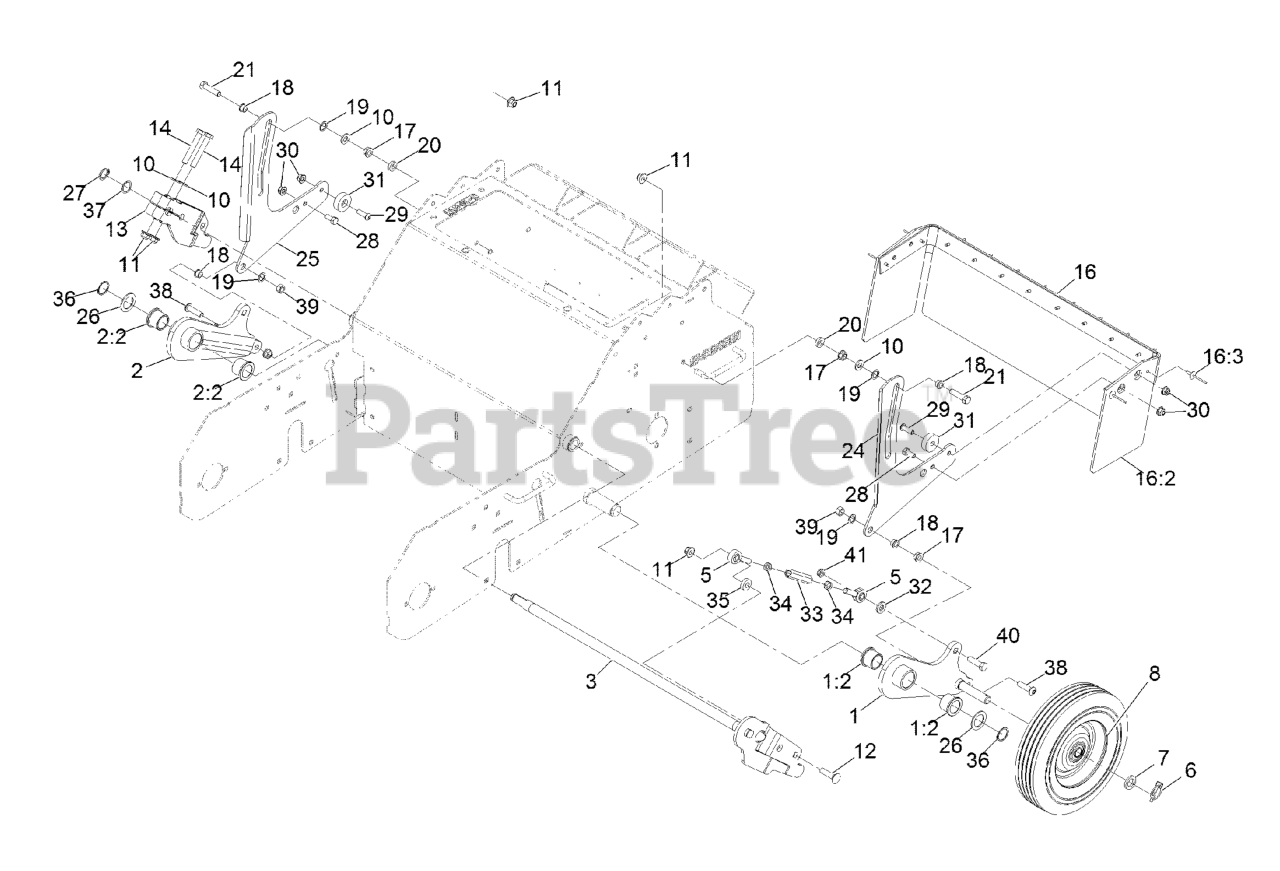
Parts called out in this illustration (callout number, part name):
1	LH WHEEL ARM ASM
1:2	BUSHING-FLANGE
2	RH WHEEL ARM ASM
2:2	BUSHING-FLANGE
3	PIVOT SHAFT ASM
5	BALLJOINT
6	PIN-KLIK
7	SPACER-BEARING
8	WHEEL, TRANSPORT
10	WASHER-FLAT
11	NUT-HF, NI
12	SCREW-CARR
13	ARM-LIFT, RH
14	SCREW-HH
16	GUARD-FOOT
16:2	FOOT-SHIELD
16:3	RIVET-POP
17	NUT-HHF, WHIZ
18	BUSHING-FLANGED
19	WASHER-NYLON
21	SCREW-HH
24	GUARD-ARM, LH
25	GUARD-ARM, RH
26	WASHER-SPACER
27	RING-RETAINING
28	SCREW-HH
29	SCREW-HSBH
30	NUT-HF, NI
31	GUIDE-ARM, TRAIL
33	ROD-LIFT LINK
34	NUT-HJ
35	SPACER
36	RING-RETAINING
37	WASHER-WAVE
38	SCREW-HSBH
39	NUT-HEX
40	SCREW-HH
